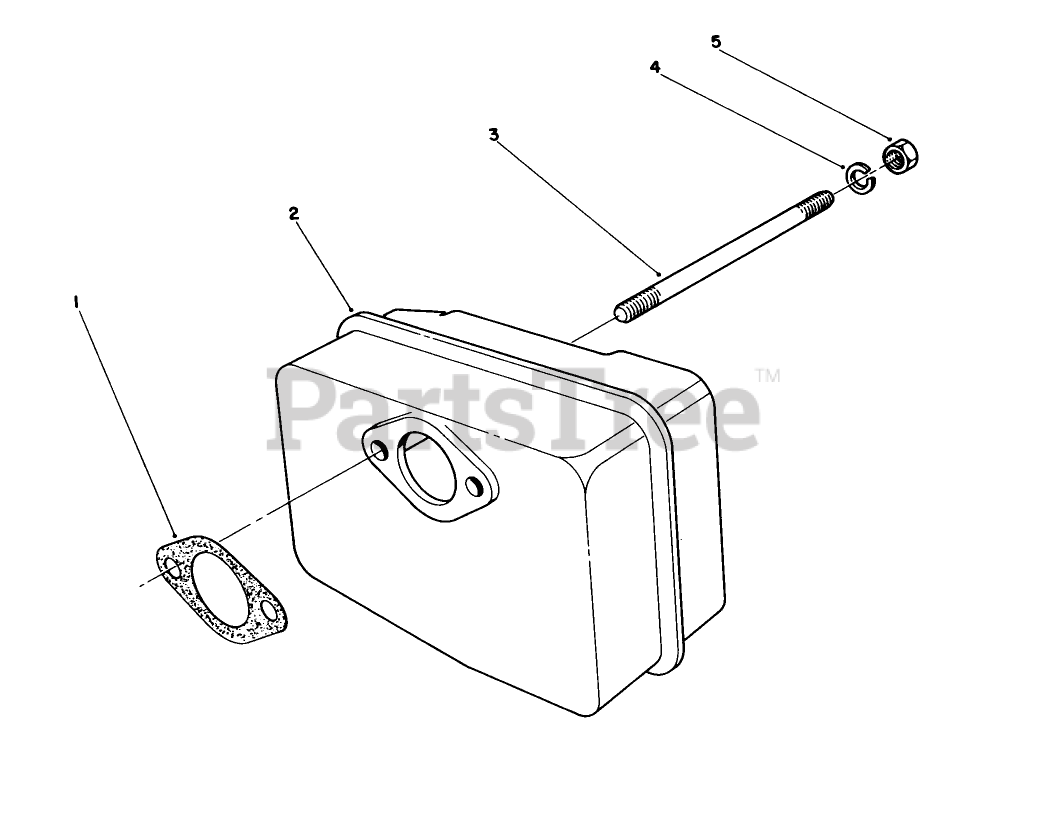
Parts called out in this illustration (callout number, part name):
1	Gasket-Muffler
2	Muffler
4	WASHER-LOCK
